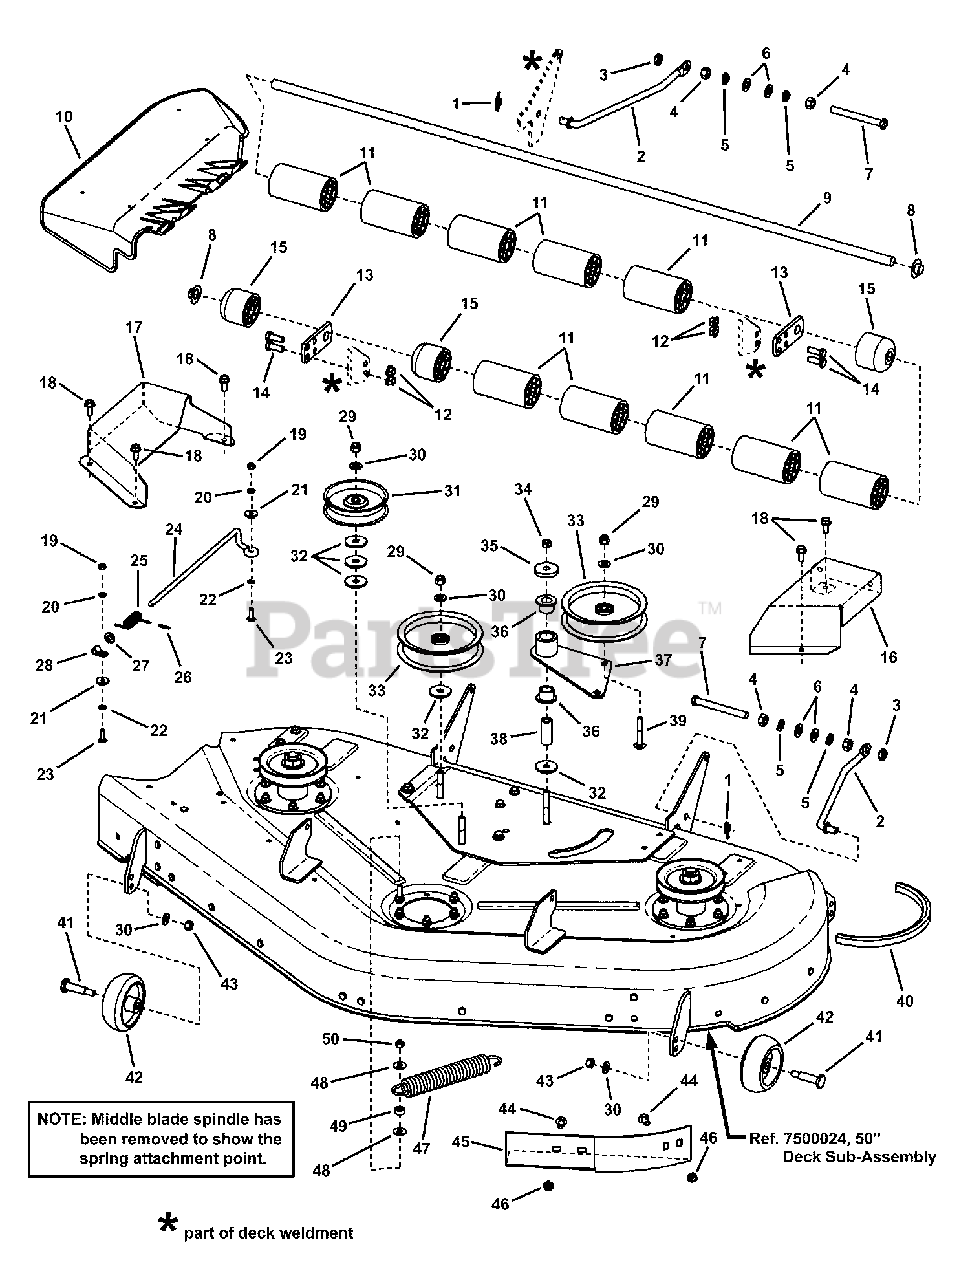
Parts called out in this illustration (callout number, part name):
1	PIN, Cotter, 1/2 Self, YZ
2	ROD, Stabilizer
3	NUT, Hex Center Lock Jam, 7/16F GR5 YZ
4	NUT, Hex, 7/16F GR5 BZ
5	WASHER, Lock, .445X.776X.1 YZ
6	WASHER, .47X.92X.065 YZ
7	CAPSCREW, Hex Head, 7/16F X4-1/4 GR5 YZ
8	NUT, Push For 5/8 Diameter Stud Capped Black
9	SHAFT, Roller, 50, Black
10	DEFLECTOR, Black
12	NUT, Hex Flange Lock, 3/8C YZ
13	BAR, Roller, 44/50, Black
14	CAPSCREW, Hex Head, 3/8C X1 GR5 YZ
15	ROLLER, Rounded
16	COVER, Spindle, RZT 44/50", Orange, LH
17	COVER, Spindle, RZT 44/50", Orange, RH
18	CAPSCREW, Hex Head Flange Taptite, 5/16C X3/4 YZ
19	NUT, Hex 1/4-20 Black 588514
20	LOCKWASHER, Spring 1/4 Black
21	WASHER, 1/4 Black
22	NUT, Push For 1/4 Diameter Thread 1/2 OD Black
23	CARRIAGE BOLT, 1/4-20X7/8 G5 Black
24	ROD, Deflector, Front
25	SPRING, Torsion
27	WASHER, 5/16 Black
28	CLAMP, Wire, 5/16 Diameter (1) .281 HOLE Black
29	NUT, Hex, 3/8C, Nylock YZ
30	WASHER, 3/8 SAE YZ
31	PULLEY, Flat Idler, 4"
32	WASHER, .406X1.5X.120 YZ
33	PULLEY, Flat Idler 5.0 X
34	NUT, Hex Center Lock, 3/8C GR5 ZP
35	WASHER, .468X1.625X.25 YZ
36	BEARING, Powdered Metal
37	WELD, Hinge Pivot
38	SPACER, Idler, Yellow
39	CARRAIGE BOLT, 3/8-16 X 2-1/4, GR5
40	BELT, RZT, 50", EL 150, B. SEC.
41	BOLT, Shoulder, 3/8F X.62, 1/2 DIA, YZ
42	WHEEL, Gage 4 X 1.5
43	NUT, Hex Center Lock, 3/8F GR5 YZ
44	CARRAIGE BOLT, 5/16C X3/4 GR5 YZ
45	BAFFLE, Blowout, Short, Plain
46	NUT, Hex Flange Lock, 5/16C GR5 YZ
47	SPRING, Idler Primary
48	WASHER, .375X.875X.083 YZ
49	SPACER, .625 OD X .340 ID X .31 L
50	NUT, Hex Center Lock, 5/16C GR5 YZ
